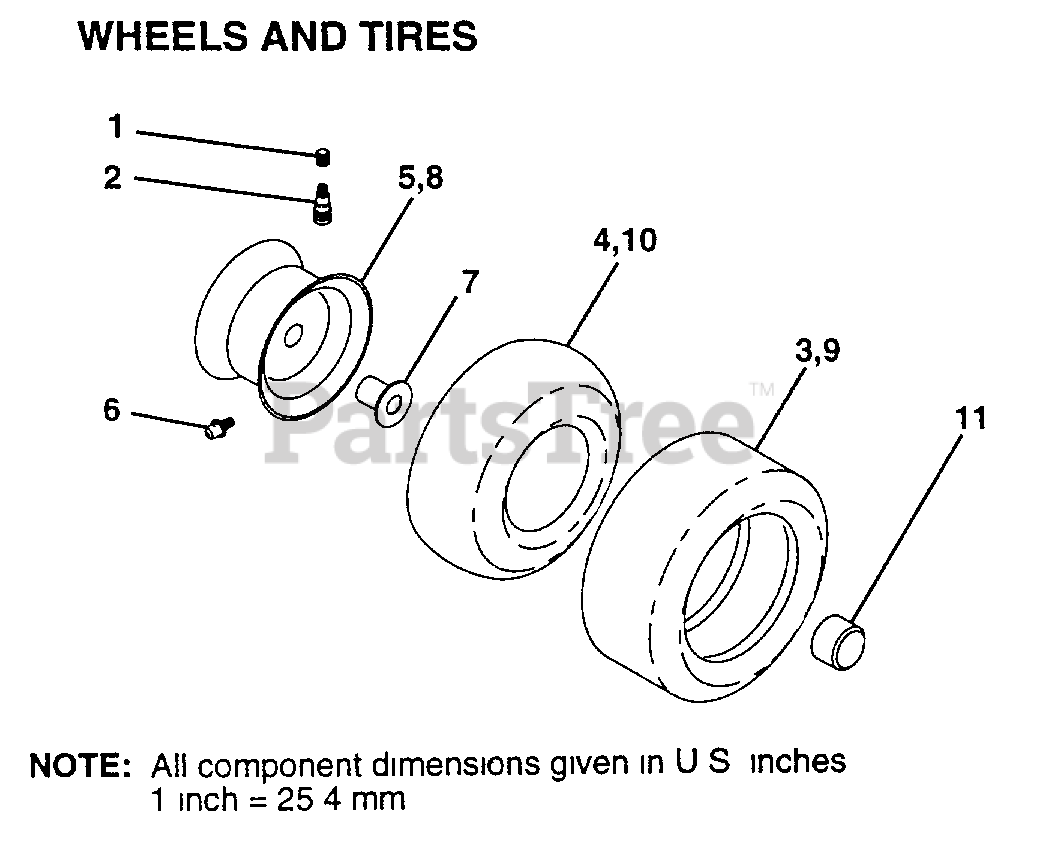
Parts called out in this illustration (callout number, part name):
1	VALVE CAP
2	VALVE STEM LT
4	TUBE.5.3/4.5/6
5	"RIM,FRT T"
6	FITTING LT
7	"FLANGE, BEARING"
8	"RIM 8"""
9	TIRE.20X8-8
10	TUBE.18X9.5-8
11	HUB CAP
